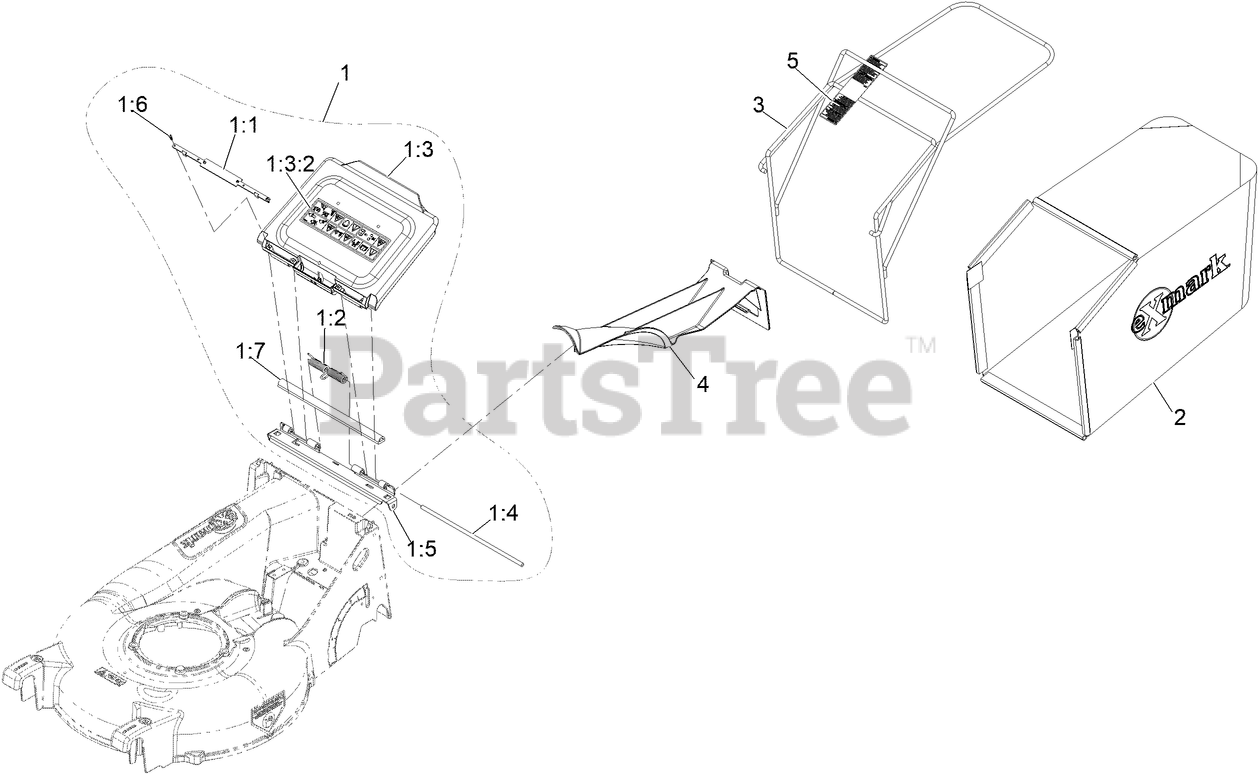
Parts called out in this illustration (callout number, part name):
1	DOOR ASM
1:1	X-REF 126-2628-03
1:2	SPRING-PLASTIC DOOR
1:3	ASM-DOOR & DECAL
1:3:2	DECAL-WARNING
1:4	PIN-DOOR PIVOT
1:5	X-REF TO 126-2636-03
1:6	SCR,TAP,6-19X7/16,PHPH, S
1:7	SEAL-EPDM FOAM BULB
2	BAG-GRASS EC21
3	WLD-BAG FRAME
4	PLUG,MULCH
5	DECAL-WARNING (BAG)
